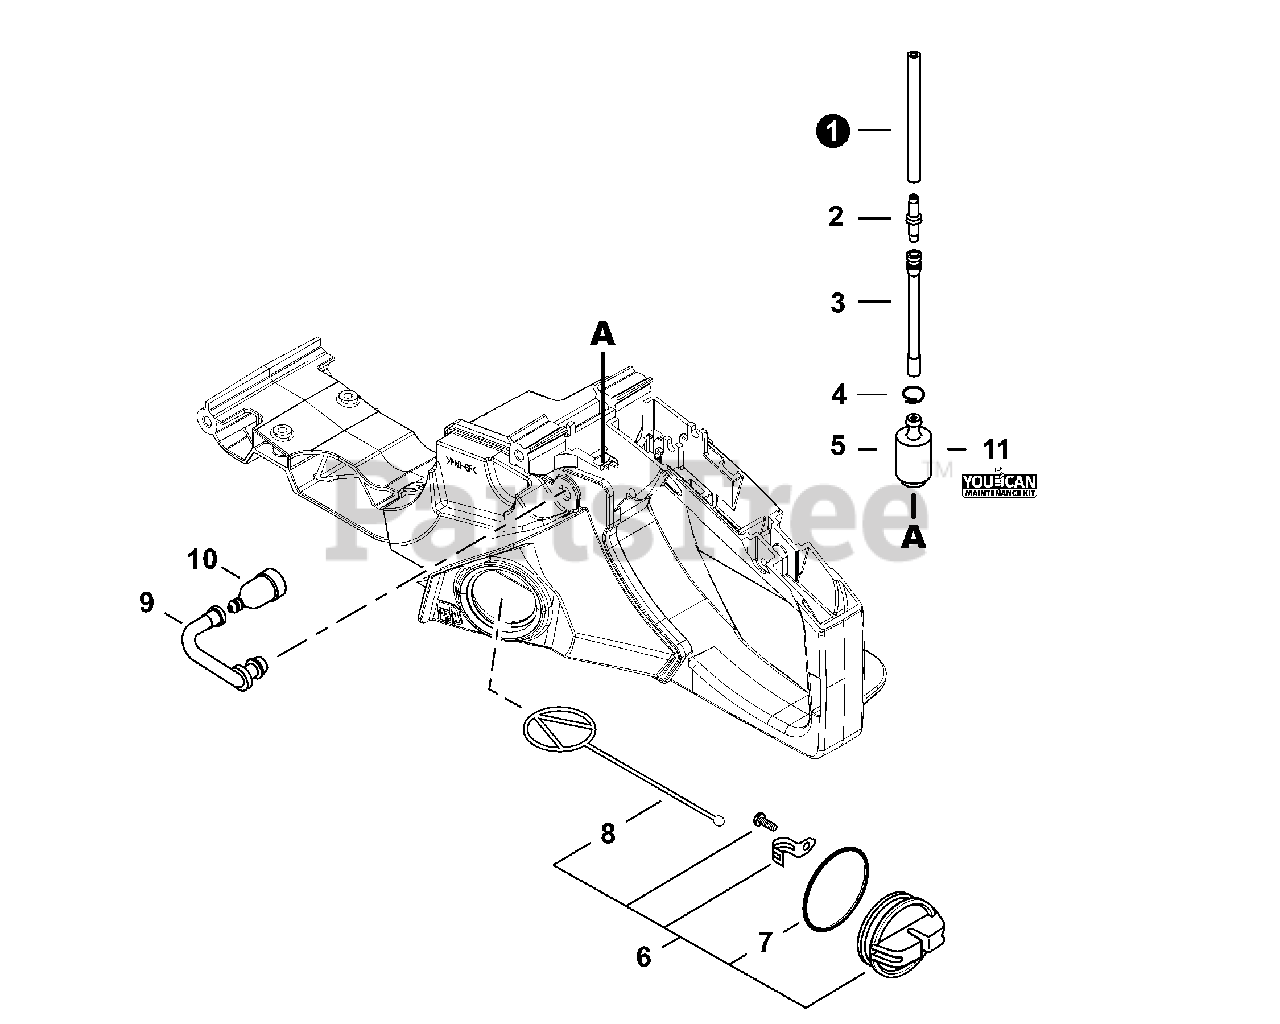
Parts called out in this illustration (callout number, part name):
1	PIPE, FUEL 3×6×75
2	CONNECTOR, PIPE
3	PIPE, FUEL
4	CLIP Ø6
5	FILTER, FUEL
6	CAP ASSY, FUEL
7	O-RING 29
8	CONNECTOR, CAP L= 60 MM
9	PIPE, FUEL VENT
10	VENT ASSY
11	TUNE-UP KIT - YOUCAN™
